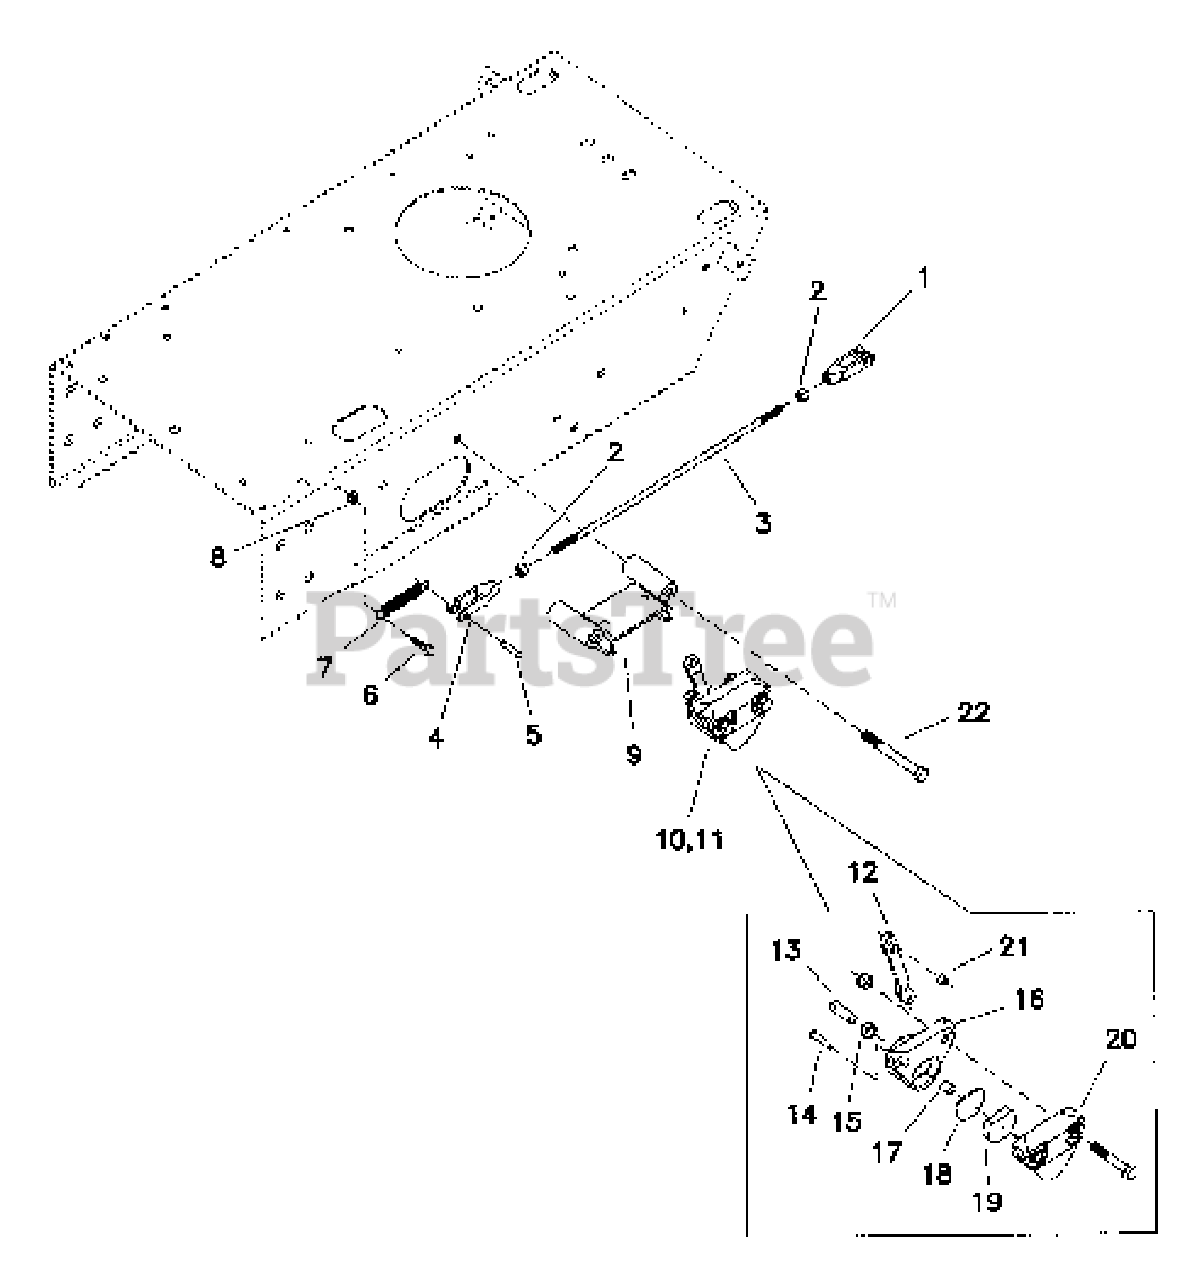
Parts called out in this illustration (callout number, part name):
1	CLEVIS, Plastic, 5/16
2	NUT, Hex, 5/16-24
3	BRAKE LINKAGE ROD
4	CLEVIS, Steel, 5/16
5	CLEVIS PIN, 1/4 x 7/8
6	CAPSCREW, Hex Head, 1/4-20 x 1
7	SPRING, Extension
8	NUT, Hex, Serrated Flange, 1/4-20
9	BRAKE CALIPER MOUNT
10	CALIPER, LH (Includes Ref 12-20)
11	CALIPER, RH (Includes Ref 12-20)
12	LEVER
13	ADJUSTER BOLT
14	LEVER PIN
15	JAM NUT
16	BRAKE HOUSING (Unavailable for replacement parts)
17	ACTUATOR PIN
18	BACK PLATE
19	BRAKE PAD
20	ANVIL
21	SPACER
22	CAPSCREW, Hex Head, 3/8-16 x 3-1/2
